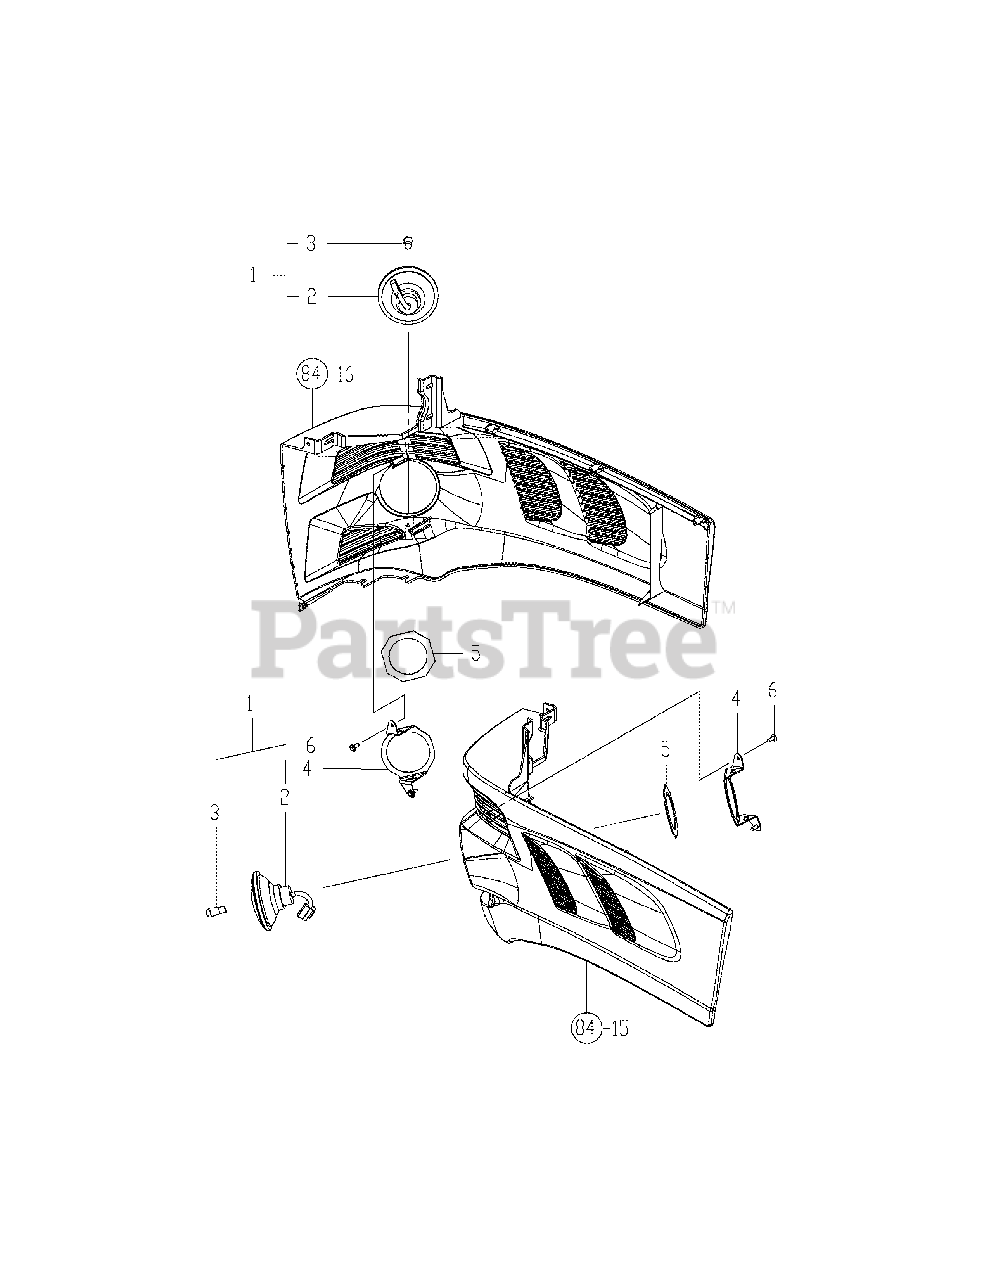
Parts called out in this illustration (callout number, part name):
1	Lamp Assy, Side
2	Case Assy, Side Lamp
5	Rubber, Side Lamp
